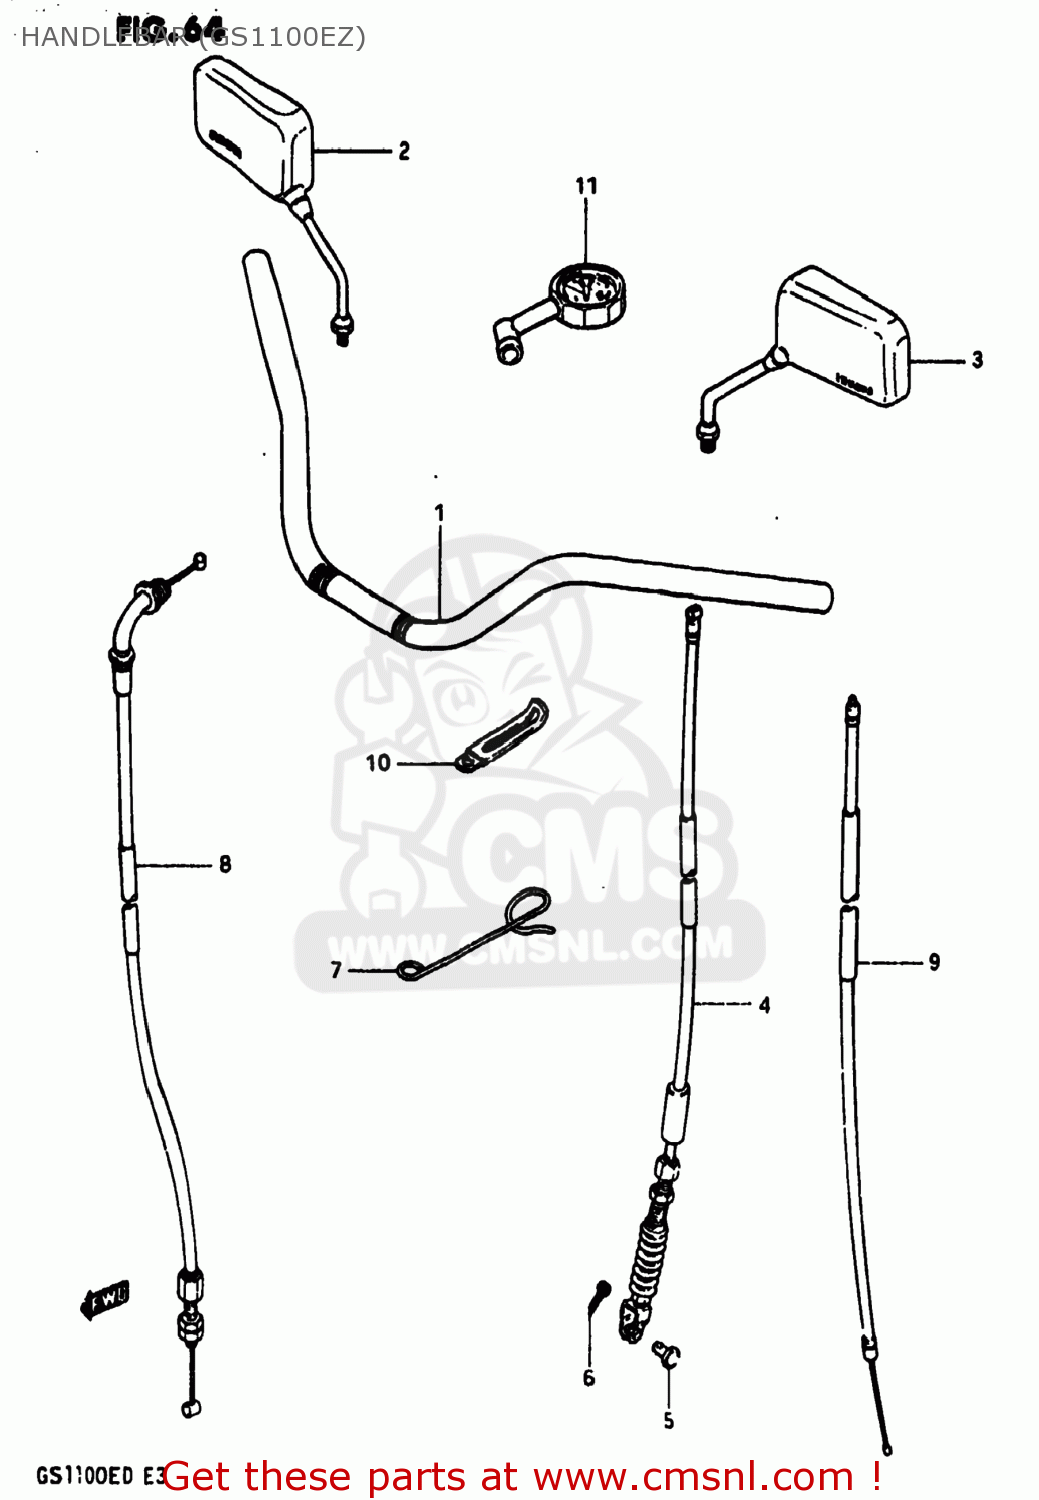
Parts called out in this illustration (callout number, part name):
1	HANDLEBAR
2	MIRROR ASSEMBLY,REAR VIEW
3	MIRROR ASSEMBLY,REAR VIEW
4	CABLE ASSEMBLY,CLUTCH
5	PIN(L:15)
6	PIN
7	GUIDE,CLUTCH CABLE
8	CABLE ASSEMBLY,THROTTLE
9	CABLE ASSEMBLY,STARTER
10	CLAMP
11	GAUGE ASSY,AIR PRESSURE
